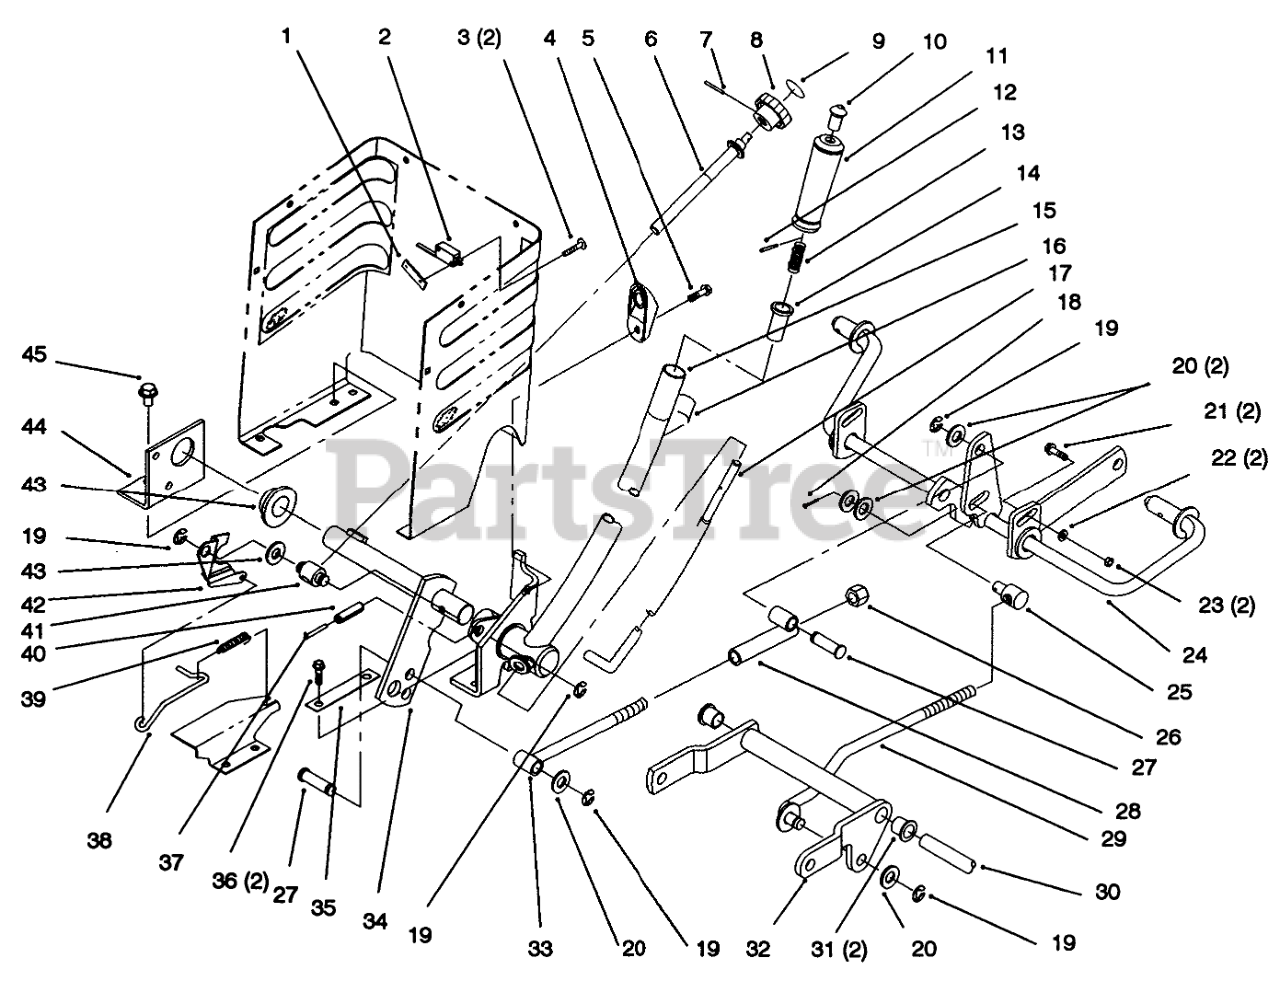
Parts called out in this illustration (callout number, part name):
1	NUT-SPEED
2	SWITCH-MICRO
3	SCREW-HH
4	WEDGE - HOC
5	SCREW-HWH
6	ROD - HOC
7	PIN-SPIROL
9	DECAL-HEIGHT KNOB
18	PIN-COTTER
19	RING-RETAINING, EXTERNAL
20	WASHER-FLAT
21	BOLT-CARR
22	WASHER-FLAT
23	NUT-LOCK, NI
24	Gage Shaft
25	ROD-TRUNNION LIFT
26	NUT-LOCK, NI
30	SHAFT-PIVOT, PEDAL
31	BUSHING-FLANGE
34	Lift Arm W.a.
36	SCREW-HWHTF
37	PIN-SPRING
38	ROD - HOC INDICATOR
39	SPRING - EXTENSION
40	PIN-ROLL
41	TRUNNION
42	PLATE - HOC GAGE
43	BEARING-FLANGE
44	Bracket-Pivot Linkage
45	SCREW-HWHTF
